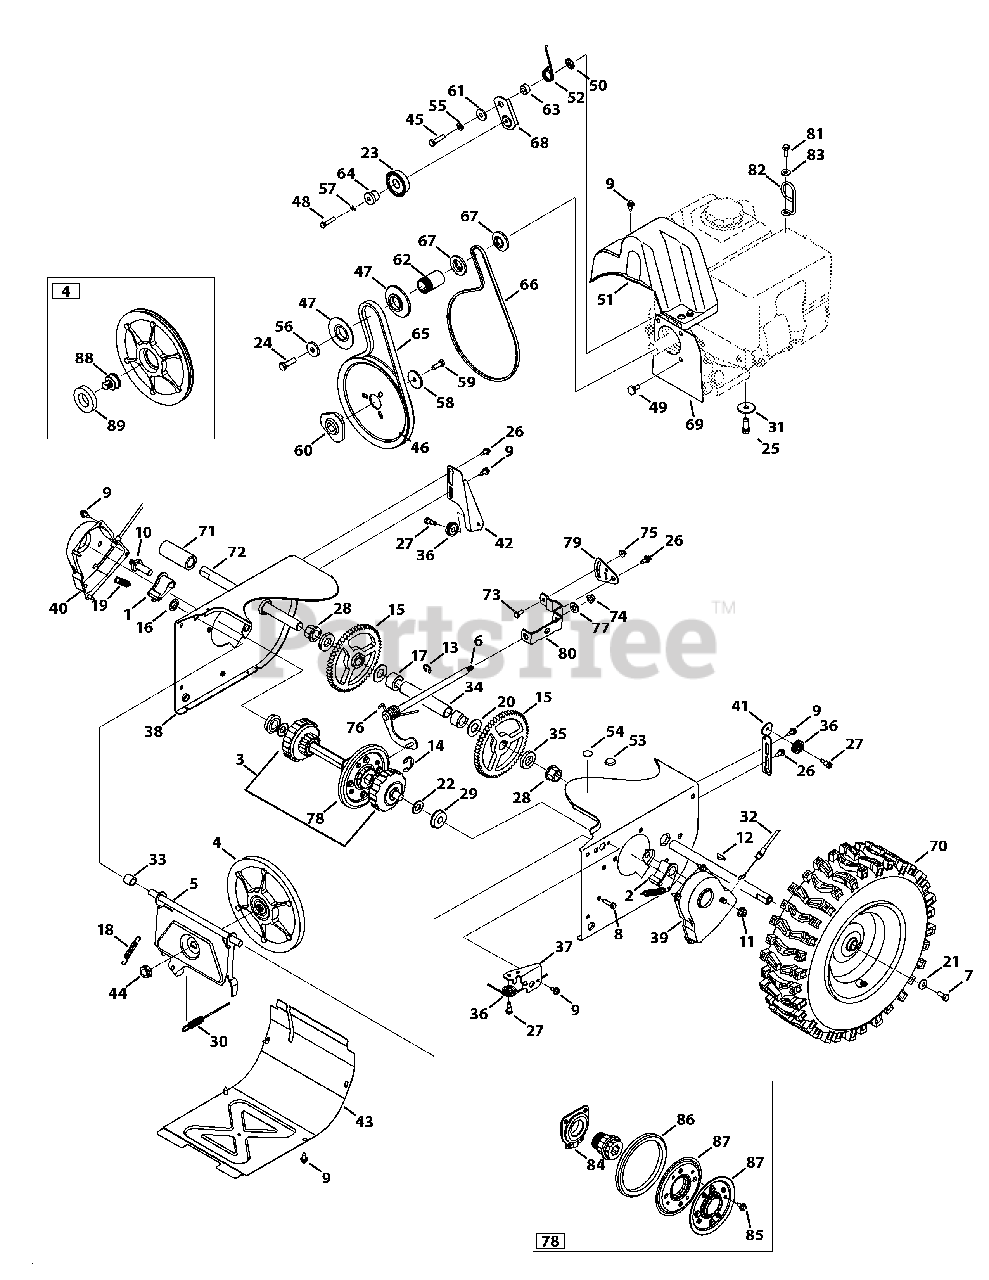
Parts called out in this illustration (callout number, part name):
1	Dogg Assembly, RH
2	Dogg Assembly, LH
3	Drive Shaft Assembly
4	Friction Wheel Disc Assembly
5	Friction Wheel Support Bracket
6	Rod Shift Assembly
7	Hex Head Screw, 5/16-24 x .750
8	Screw, 1/4-20 x 1.000
9	Screw, 1/4-20 x .625
10	Actuator Shaft
11	Nut, Flangelock, 3/8-16
12	Hi-Pro Key, 3/16 x 3/4 DIA
14	Retainer Ring
16	Nut, Speed, .500
17	Spacer, .76 x .75
18	Extension Spring, .380 x 2.500
19	Extension Spring, .500 x 1.71
20	Washer, Flat, .76 x 1.49
21	Washer, Bell, .340 x .872
22	Washer, Flat, .58 x 1.125
23	Idler Pulley Assembly
24	Hex Head Screw, 3/8-24 x 1.25
25	Taptite Sems Screw, 3/8-16 x 1.000
26	Screw, Shoulder, .368 x .113 x 1/4-20
27	Screw, Shoulder, .340 x .335 x 1/4-28
28	Hex Flange Bearing, .75 ID
29	Ball Bearing, .5625 x 1.375 x .4375
30	Drive Clutch Cable
31	Washer, Flat, .38 x 1.38
32	Steering Cable
33	Spacer, .508 x .75
34	Axle Support Tube
35	Spacer, Axle
36	Cable Roller
37	Auger Cable Guide Bracket
38	Wheel Drive Frame
39	Shaft Retainer, LH
40	Shaft Retainer, RH
41	Auger Clutch Cable Guide Bracket
42	Drive Clutch Cable Guide Bracket
44	Nut, Flange, 5/8-18
45	Hex Head Screw, 5/16-24 x 1.25
46	Auger Pulley, 8.1 x .5
47	Pulley, Half, 2.600
48	Taptite Screw, 1/4-20 x 1.250
49	Shoulder Screw, .500 x .145
50	Nut, Push-On, .25 Dia.
51	Belt Cover, (526/528/530 SWE)
51	Belt Cover (524 SWE)
52	Spring, Torsion, .850 x .333
53	Plug, 3/8 ID
54	Plug, 1/2 ID
55	Washer, Lock, 5/16
56	Washer, Flat, .406 x 1.25
57	Washer, Lock, 1/4
58	Washer, Flat, .34 x 1.50
59	Hex Head Screw, 5/16-24 x .875
60	Pulley Adapter, .75 DIA
61	Spacer, Shoulder, .3175 x .500
62	Spacer, .875 x 1.185
63	Spacer, .340 x .750
64	Spacer, Shoulder, .260 x .785
65	Belt, .500 x 37 (526/528/530 SWE)
65	Belt, .500 x 35.06 (524 SWE)
66	Belt, 3/8 x 35.68 (526/528/530 SWE)
66	V Belt, 3/8 x 34.4 (524 SWE)
67	Pulley, Half, 3/8 x 1.7160
68	Drive Idler Bracket
69	Cover Plate (526/528/530 SWE)
69	Cover Plate (524 SWE)
70	Wheel, LH (528 SWE, 530 SWE)
70	Wheel, RH (528 SWE, 530 SWE)
70	Wheel, LH (524 SWE, 526 SWE)
70	Wheel, RH (524 SWE, 526 SWE)
71	Spacer, 1.25 x .75 x 3.00
72	Axle, .75 x 11.12
73	Hex Head Screw, 1/4-20 x .620
74	Nut, Flange Lock, 5/16-18
75	Nut, Flange Lock, 1/4-20
76	Spring, Torsion, .750 x .968
77	Washer, Flat, .469 x .875 x .105
78	Friction Wheel Assembly
79	Speed Selector Pivot Bracket
80	Speed Selector Shift Bracket
81	Hex Head Screw, 1.25 x 20
82	Cable Guide (524 SWE)
82	Cable Guide (526/528/530 SWE)
83	Washer, Flat, .330 x .630
84	Bearing Assembly, Friction Wheel
85	Screw, 1/4-14 x .625
86	Friction Wheel, 5.5 OD
87	Friction Wheel Plate
88	Friction Pin, Disc Bearing
89	Ball Bearing, 30 x 55 x 13
